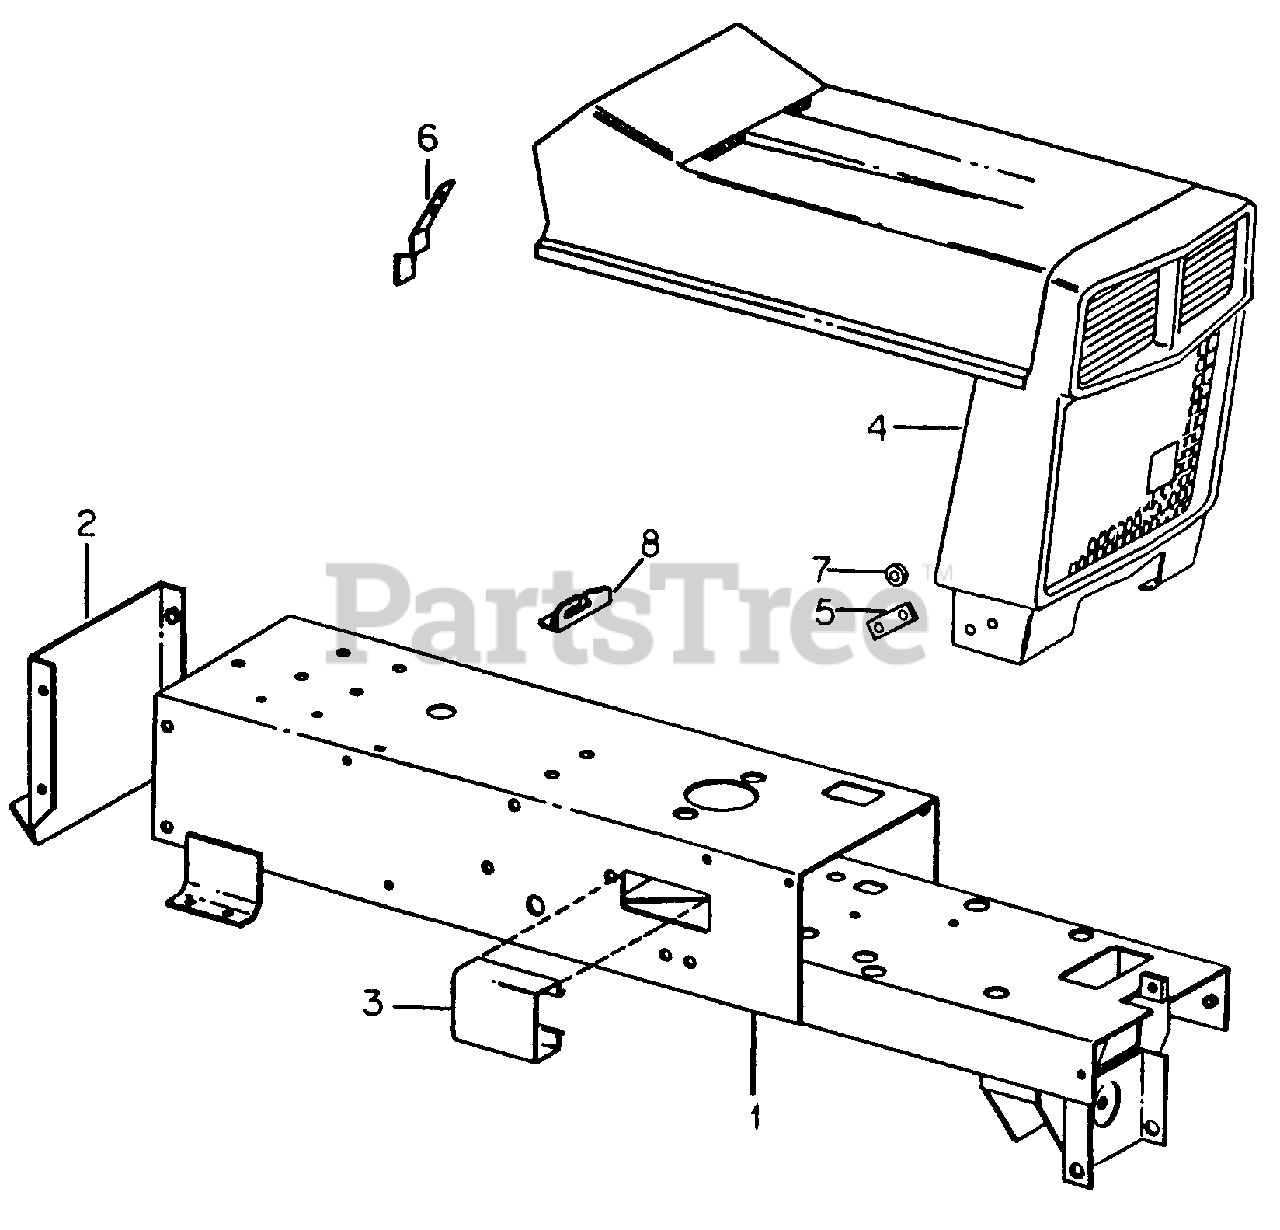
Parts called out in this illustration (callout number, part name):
1	Frame Assy - 382 Gear Drive
2	Drawbar Assy
3	Cover, Steering Arm
4	Hood Assy
5	Bracket, Hood Front Mounting
6	Latch, Hood
7	Spacer, Rubber
8	Bracket, Shifter Index
